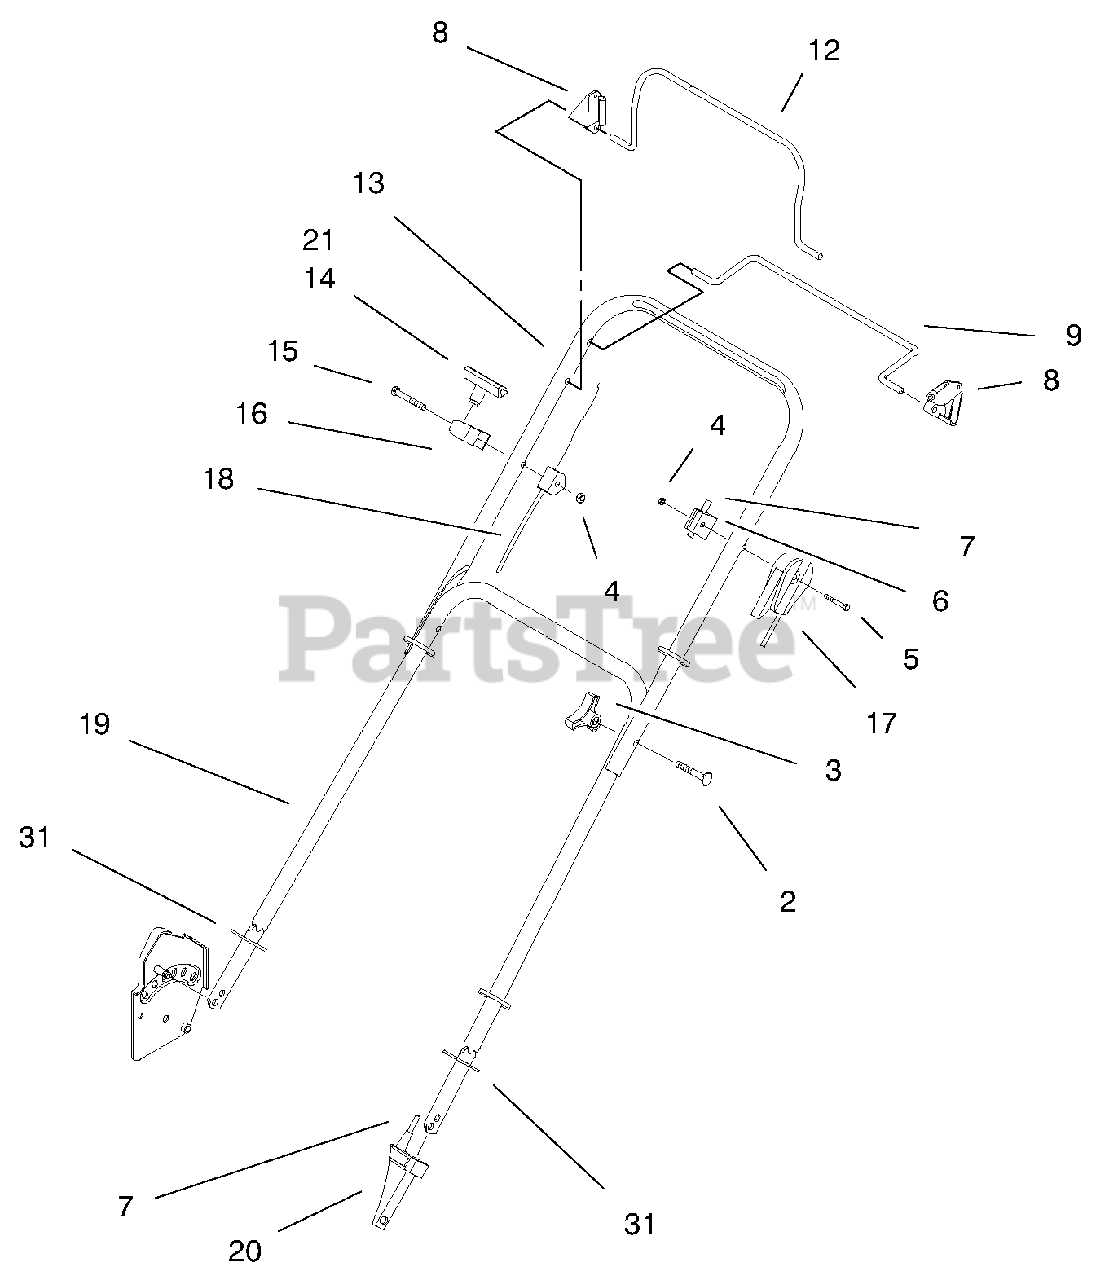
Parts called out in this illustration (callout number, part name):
2	Screw-Handle
3	Knob
4	Nut-Lock
5	Screw-Hex Hd. Cap
6	Anchor-Cable Upper
7	Cable-Traction
8	Stop-Pivot
9	Bail-SP Control
12	Bail-Flywheel Brake
13	Handle-Section Upper
14	Handle-Starter
15	Screw-Hex Hd. Cap
16	Guide-Rope
17	Cable-Throttle 2 Cycle
18	Cable-Flywheel Brake
19	Handle Section-Lower
20	Anchor-Cable SP Lower
21	Clip-Rope Insert
31	Handle-Guard
